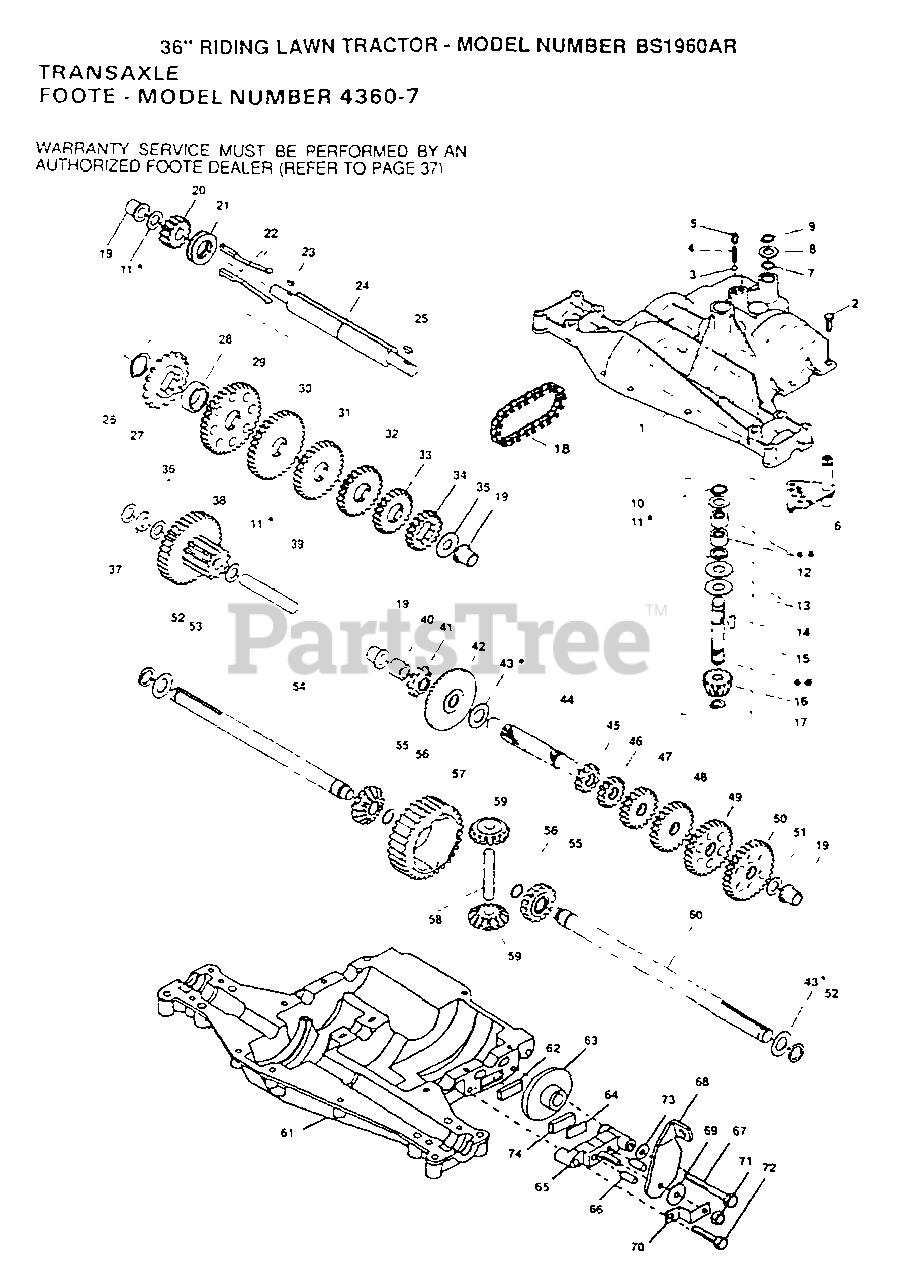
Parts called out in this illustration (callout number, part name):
1	HOUSING UPPER
3	BALL DETENT
4	SPRING, DETENT
5	SCREW, SET
6	ASSY SHIFTER
8	WASHER PLAIN
9	RING RETAINING
10	RING RETAINING
11	WASHER PLAIN
11	WASHER, PLAIN .632 X 1.00 X .026
11	WASHER, PLAIN .632 X 1.00 X .060
13	WASHER, PLAIN .632 X 1.38 X .046
14	KEY WOODRUFF #9
15	ASSY KIT INPUT SHAFT
16	PINION, BEVEL, 14 TEETH
17	RING, RETAINING
18	CHAIN, 24 PITCHES
19	BEARING, FLANGE
20	GEAR SPUR, 14 TEETH
21	COLLAR CLUTCH
22	KEY CLUTCH
23	KEY WOODRUFF #3
24	SHAFT INTERMEDIATE
25	KEY, WOODRUFF, #61
26	RING, RETAINING
27	SPROCKET, 18 TEETH
29	GEAR, SPUR, 37 TEETH
30	GEAR, SPUR, 35 TEETH
31	GEAR, SPUR, 30 TEETH
32	GEAR, SPUR, 25 TEETH
33	GEAR, SPUR, 22 TEETH
35	WASHER, PLAIN .640 X 1.37 X .061
36	WASHER, PLAIN .632 X 1.00 X .026
37	SPACER .630 X 1.00 X .169
38	ASSY GEAR COMB 12&35 TEETH
39	SHAFT IDLER
40	SPACER .635 X .875 X .755
41	SPROCKET, 9 TEETH
42	GEAR, BEVEL, 42 TEETH
43	WASHER PLAIN
43	WASHER, PLAIN .758 X 1.25 X .031
44	SHAFT, DRIVE
45	GEAR, SPUR, 12 TEETH
46	GEAR SPUR, 15 TEETH
47	GEAR, SPUR, 20 TEETH
48	GEAR, SPUR, 25 TEETH
49	GEAR, SPUR, 28 TEETH
50	GEAR, SPUR, 31 TEETH
51	WASHER, PLAIN .632 X 1.00 X .060
53	WASHER PLAIN
54	AXLE LEFT HAND
55	GEAR, MITER, 15 TEETH
56	RING, RETAINING
57	GEAR, SPUR, 32 TEETH
58	SHAFT, CROSS
59	GEAR, MITER, 15 TEETH
60	AXLE, R.H.
61	HOUSING LOWER
62	PUCK, FRICTION
63	DISC, BRAKE
65	JAW, BRAKE
66	PIN, DOWEL
67	SCREW TAPPING
68	LEVER, ACTUATING
69	WASHER, PLAIN .321 X 1.00 X .055
70	BRACKET, ANTI-ROTATION
71	LOCKNUT 5/16-24
72	SCREW TAPPING
73	WASHER PLAIN
74	PUCK, FRICTION
